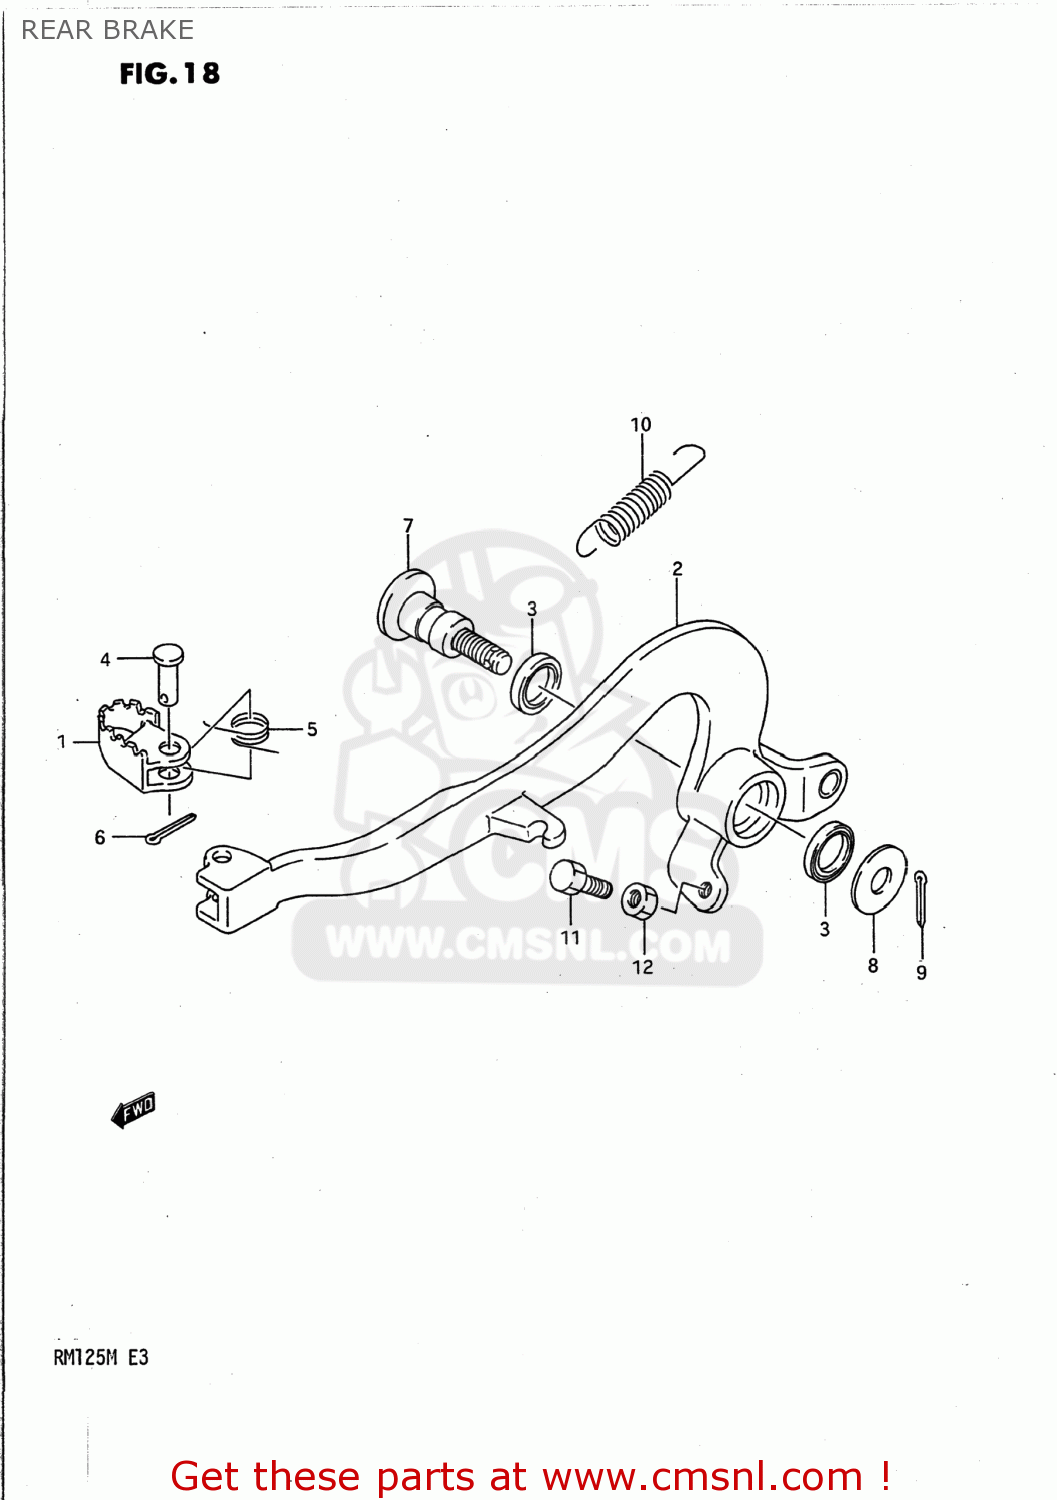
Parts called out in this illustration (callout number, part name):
1	PEDAL,BRAKE
2	ARM COMP,BRAKE PEDAL
3	SEAL,OIL(15X21X3)
4	PIN(6X23.5)
5	SPRING
6	PIN
7	SHAFT,BRAKE PEDAL
8	WASHER
9	PIN 20X20
10	SPRING
11	BOLT(6X23)
12	NUT
